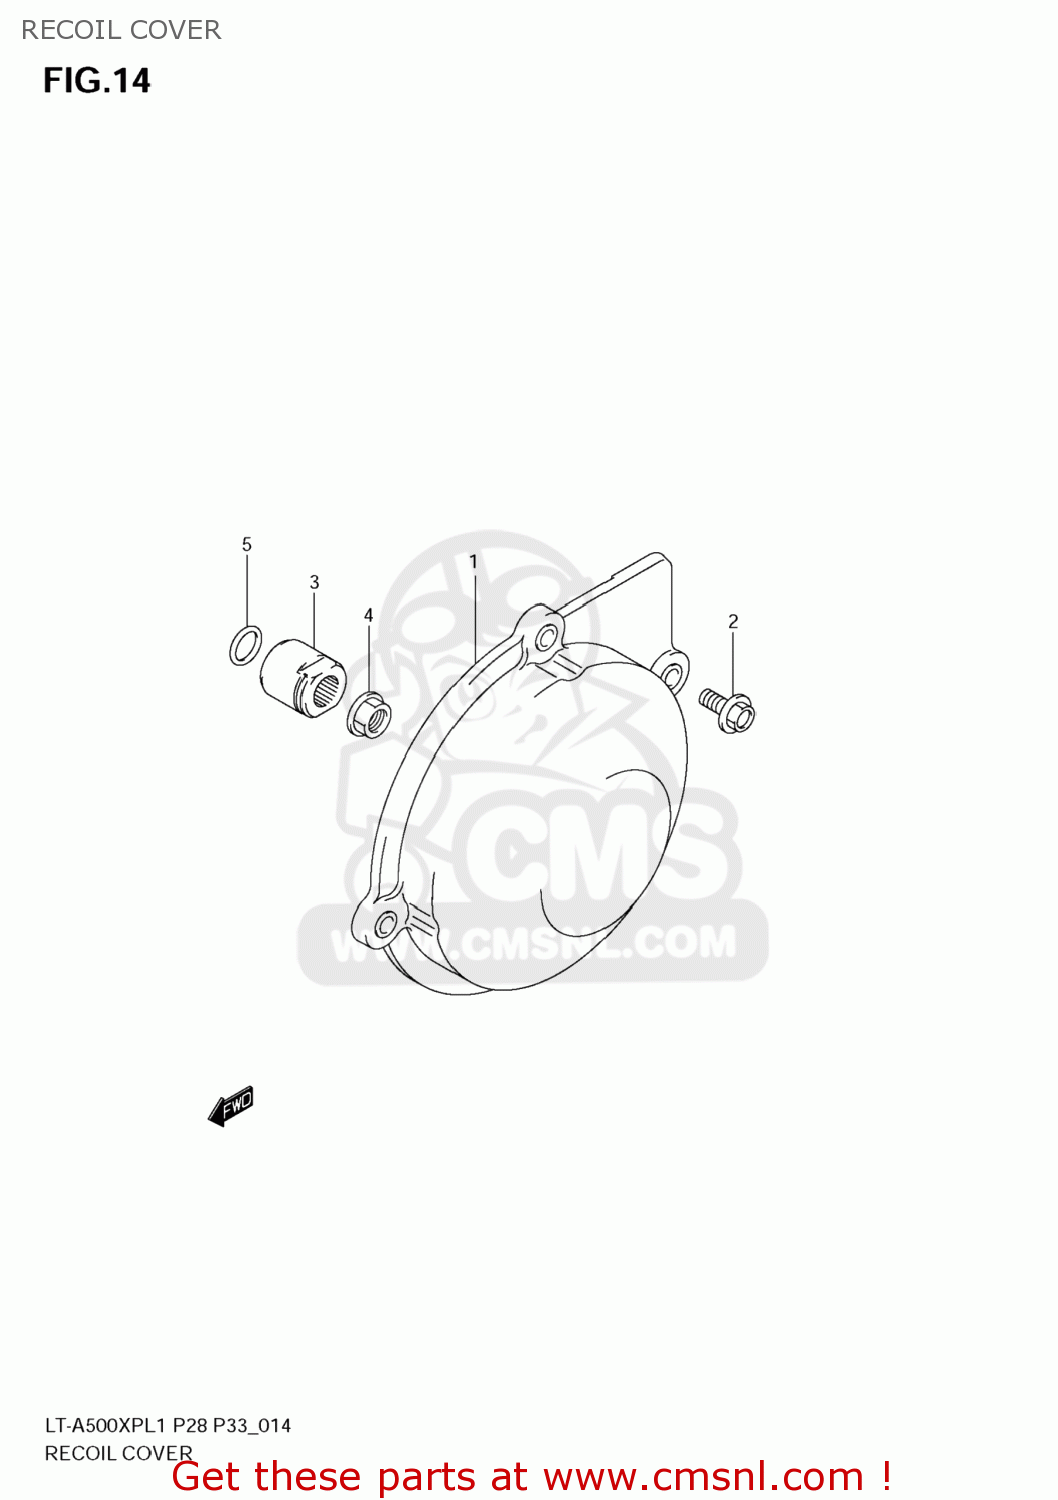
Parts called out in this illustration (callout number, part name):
1	COVER,RECOIL
2	BOLT(6X14)
3	SPACER,CRANKSHAFT,L
4	NUT
5	O RING(D:1.9,ID:12.6)
